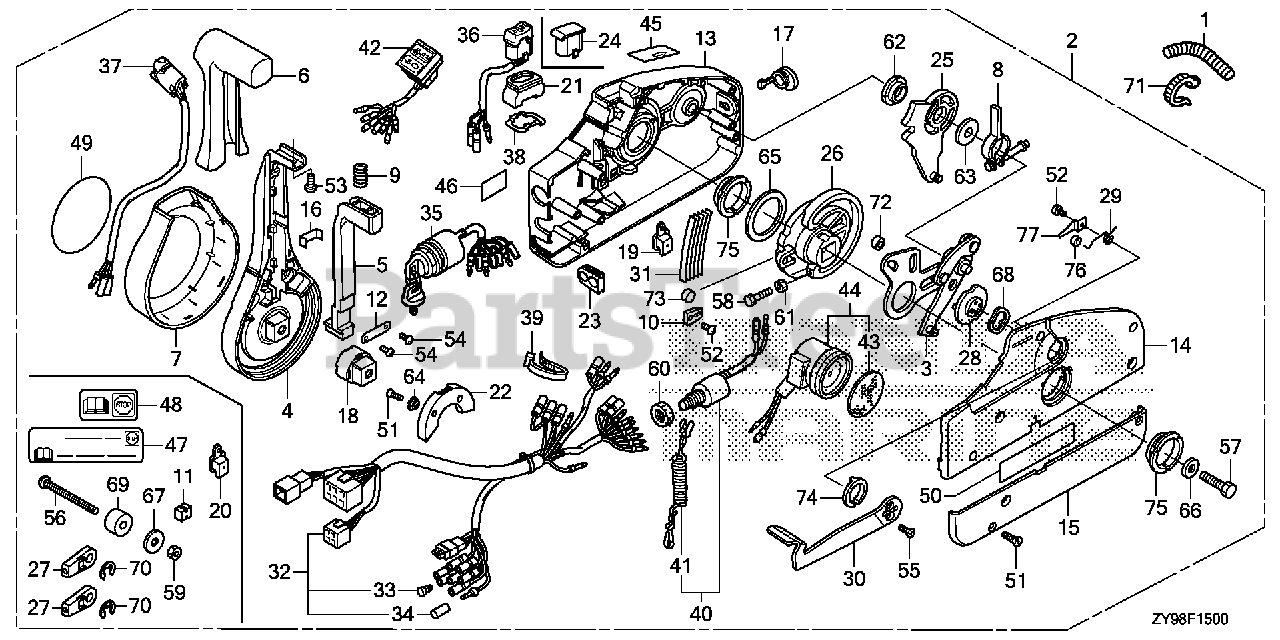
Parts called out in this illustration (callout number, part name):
1	TUBE, CORRUGATE (28MM)
2	BOX ASSY., REMOTE CONTROL (TROLLING CONTROL)(NHK MEC)
3	PLATE ASSY.
4	LEVER, HAND
5	ARM, NEUTRAL LOCK
6	GRIP
7	COVER, LEVER
8	ARM ASSY., BRAKE
9	SPRING (2)
10	CLIP, DETENT
11	SPACER (1) (LOOSE PARTS)
12	BRACKET
13	HOUSING, FR.
14	HOUSING, RR.
15	PANEL, BACK
16	BRACKET, WIRE CLAMP
17	CAP, RUBBER
18	ADJUSTER
19	COVER, POWER TRIM-TILT WIRE
20	COVER, POWER TRIM-TILT WIRE (LOOSE PARTS)
21	SEAL, RUBBER
22	HOLDER, NEUTRAL LOCK
23	GROMMET, WIRE (14)
24	CAP, TROLLING CONTROL SWITCH BLANK
25	GEAR ASSY., SHIFT
26	GEAR, DRIVE
27	TERMINAL, CABLE (LOOSE PARTS)
28	DRUM ASSY., FREE THROTTLE
29	SPRING (1)
30	LEVER, FREE THROTTLE
31	SPRING, DETENT
32	CABLE ASSY., REMOTE CONTROL (B)
32	CABLE ASSY., REMOTE CONTROL (B)(TROLLING CONTROL)
33	PLUG, CONNECTOR (INNER) (TROLLING CONTROL)
34	PLUG, CONNECTOR (OUTER)
35	SWITCH ASSY., COMBINATION
36	SWITCH ASSY., TROLLING CONTROL
37	SWITCH ASSY., POWER TRIM-TILT
38	PLATE, SWITCH
39	BAND, WIRE
40	SWITCH ASSY., EMERGENCY STOP
41	WIRE, EMERGENCY
42	LAMP ASSY., INDICATION
43	PLATE, TURN SIGNAL BUZZER
44	BUZZER, WARNING
45	MARK, FAST IDLE
46	MARK, EMERGENCY STOP (US)
47	MARK, EMERGENCY STOP (US) (LOOSE PARTS)
49	MARK, EMBLEM
50	LABEL, SIGP
51	SCREW (5X18)
52	SCREW (4X6)
53	SCREW (5X10)
54	SCREW (4X10)
55	SCREW (5X12)
56	SCREW (6X90) (LOOSE PARTS)
57	BOLT (8X50)
58	BOLT (5X25)
59	NUT (6MM) (LOOSE PARTS)
60	NUT, HEX. (16MM)
61	NUT (5MM)
62	BEARING (1)
63	WASHER (3)
64	WASHER (4)
65	WASHER (5)
66	WASHER (8MM)
67	WASHER (7) (LOOSE PARTS)
68	WASHER, WAVE
69	SPACER (2) (LOOSE PARTS)
70	E-RING (6MM) (LOOSE PARTS)
71	BAND, SELF-LOCK
72	ROLLER, DRIVE GEAR CAM
73	ROLLER
74	BEARING (2)
75	BEARING (3)
76	ROLLER, FREE THROTTLE
77	CLIP, ROLLER
